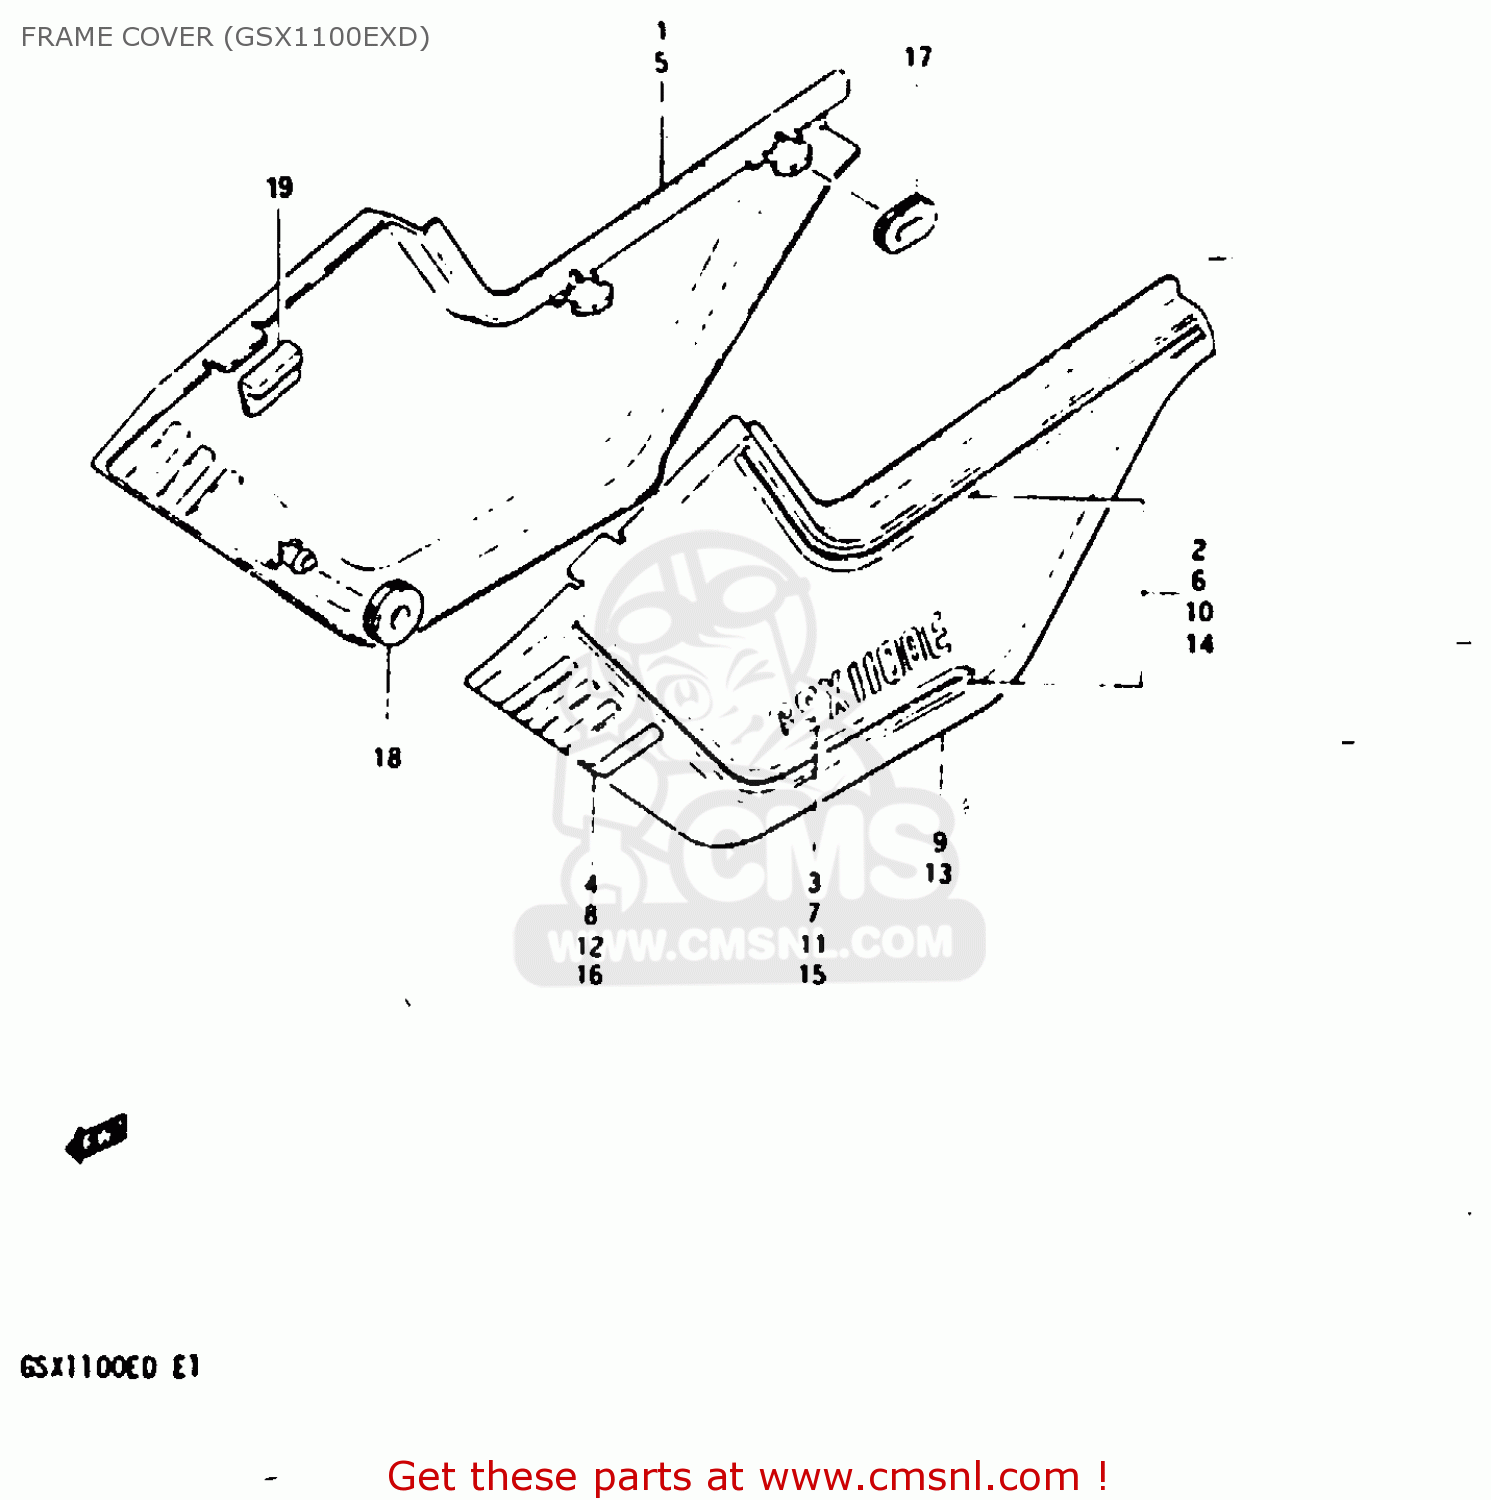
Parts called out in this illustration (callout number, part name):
1	COVER, FRAME RH (BLACK)
2	TAPE SET, FRAME COVER RH
3	EMBLEM, LH
4	LABEL, DENT
5	COVER, FRAME RH (RED)
6	TAPE SET, FRAME COVER RH
7	EMBLEM, LH
8	LABEL, DENT
9	COVER, FRAME LH
10	TAPE SET, FRAME COVER LH
11	EMBLEM, LH
12	EMBLEM,FRAME COVER,CENTER
13	COVER, FRAME LH
14	TAPE SET, FRAME COVER LH
15	EMBLEM, LH
16	EMBLEM,FRAME COVER,CENTER
17	CUSHION
18	CUSHION
19	CUSHION,FRAME COVER
